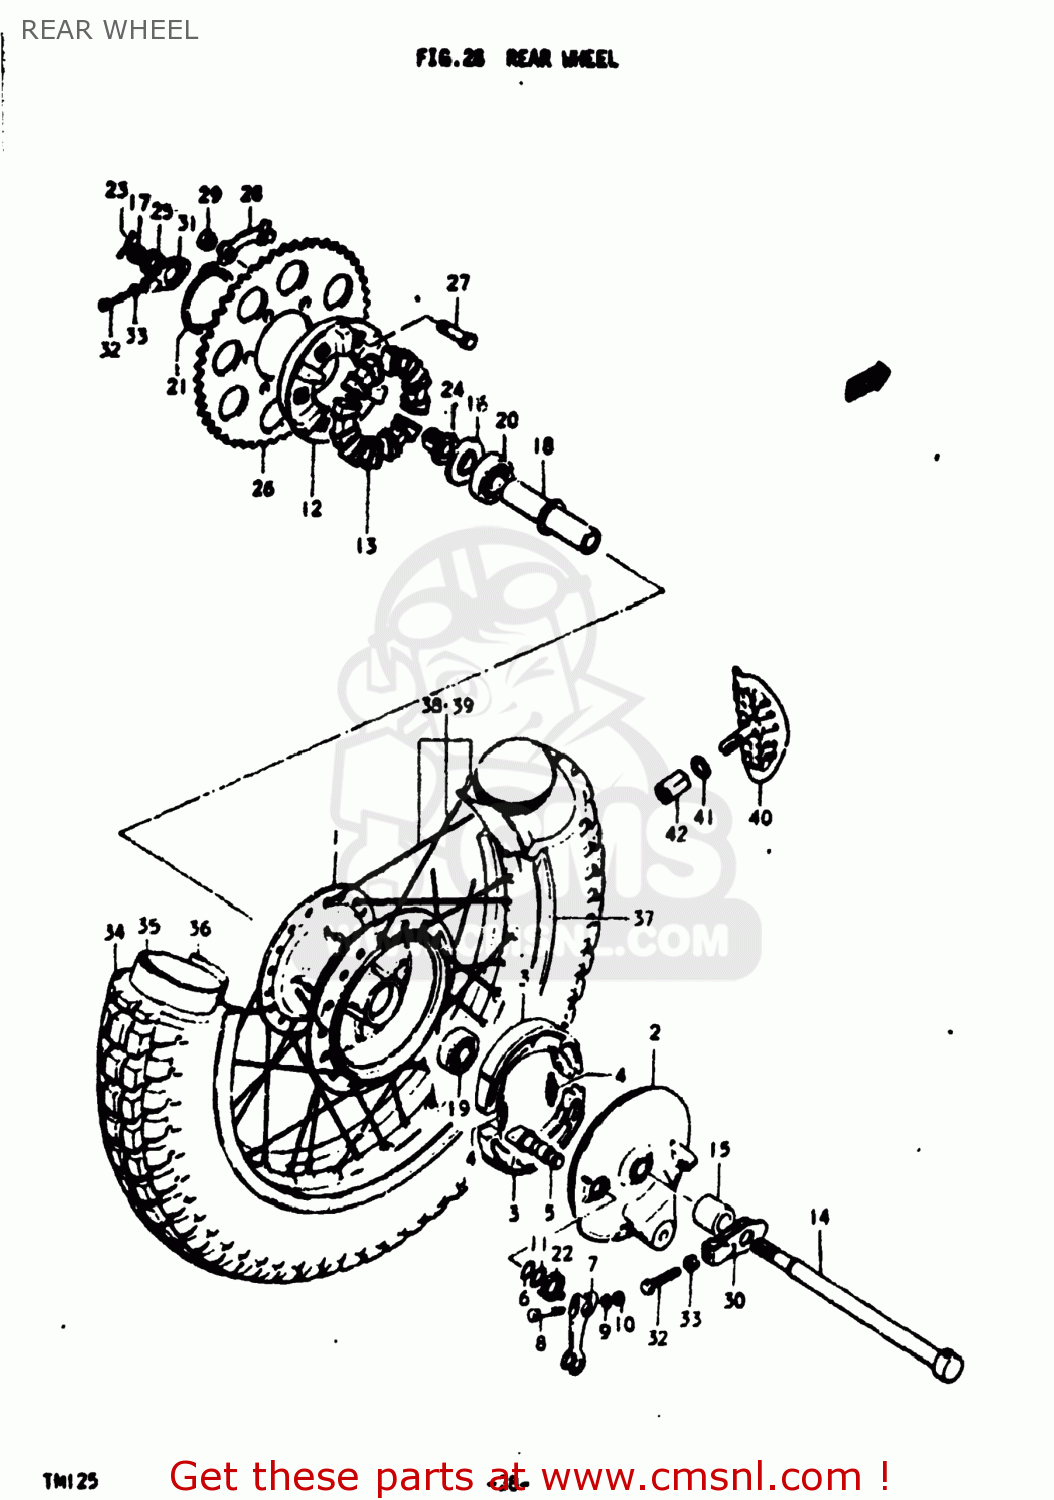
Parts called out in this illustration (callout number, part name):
0	WHEEL SET,REAR
1	HUB,REAR
2	PANEL,REAR HUB
3	SHOE,BRAKE
4	SPRING(L:34)
5	CAM,FRONT BRAKE
6	O RING(D:2.5,ID:11.4)
7	LEVER,REAR BRAKE CAM
8	BOLT
9	WASHER
10	NUT
11	WASHER(12.5X20X1)
12	DRUM,REAR SPROCKET MOUNT
13	ABSORBER,RR WHEEL HUB SHOCK
14	AXLE,REAR
15	SPACER
16	SPACER,RR AXLE,L
17	NUT 12MM
18	SPACER,REAR HUB BEARING
19	BEARING
20	BEARING
21	CIRCLIP
22	SPRING
23	COTTER PIN
24	SPACER,CHAIN ADJUSTER,L
25	NUT
26	SPROCKET,REAR
27	BOLT(8X32)
28	WASHER
29	NUT
30	ADJUSTER,CHAIN
31	ADJUSTER,CHAIN
32	BOLT
33	NUT
34	TIRE
35	TUBE ASSEMBLY,WHEEL,INNER
36	PROTECTOR,WHEEL,INNER
37	RIM,REAR WHEEL
38	SPOKE SET,REAR
39	SPOKE SET,REAR
40	STOPPER,BEAD
41	WASHER
42	NUT
